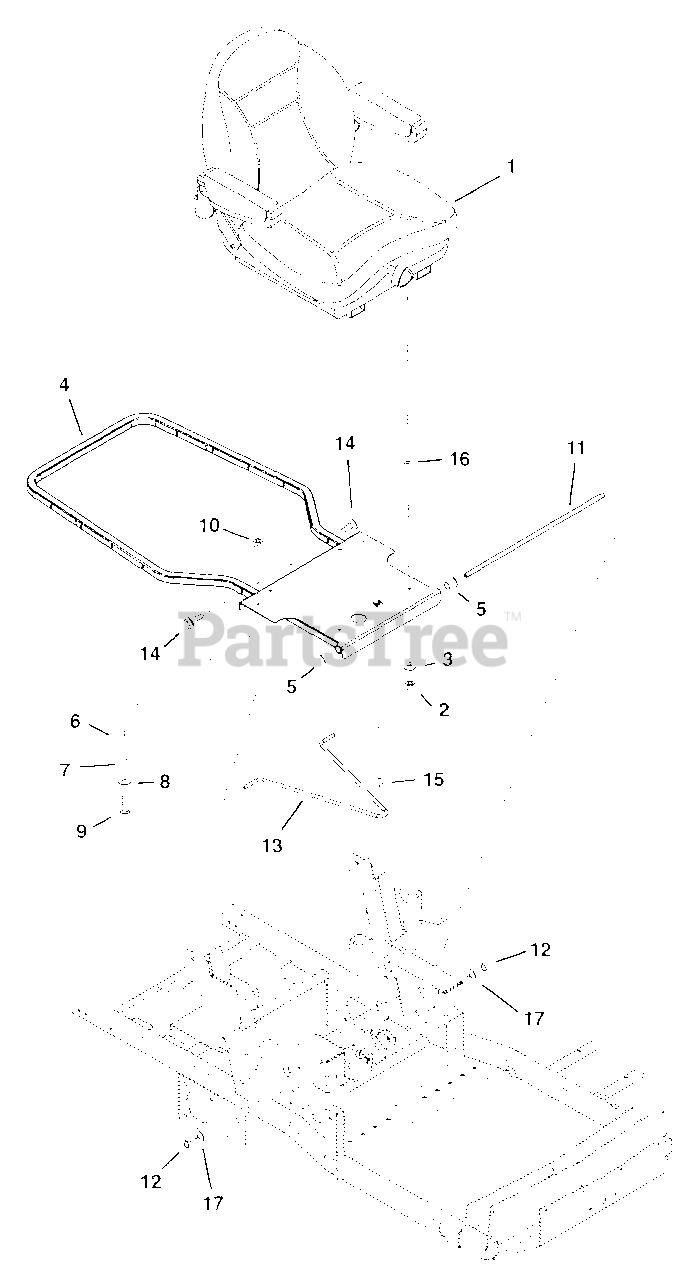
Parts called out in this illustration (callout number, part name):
1	Seat, Suspension
2	Nut-Locking-Center M8-1.25
3	Washer-Flat-Steel .38 x .875 x .083
4	Weldment- Hood Frame
5	Bushing-Flange .515 x .750 x .745 x 1.00
6	Bumper-Seat
7	Bushing-Sleeve .265 x .375 x .250
8	Washer-Flat-Steel .312 x .734 x .065
9	Bolt-Hex .25-20 x .75 Grade 5
10	Nut-Locking-Center .25-20
11	Rod-Seat Frame Pivot
12	Ring-Retaining-External .500 x .050
13	Rod-Prop
14	Screw-Tapping .25-20 x .50 Hex Washer Head
15	Clip
16	Bushing-Sleeve .377 x .624 x .235
17	Washer-Flat-Steel .505 x 1.00 x .062
